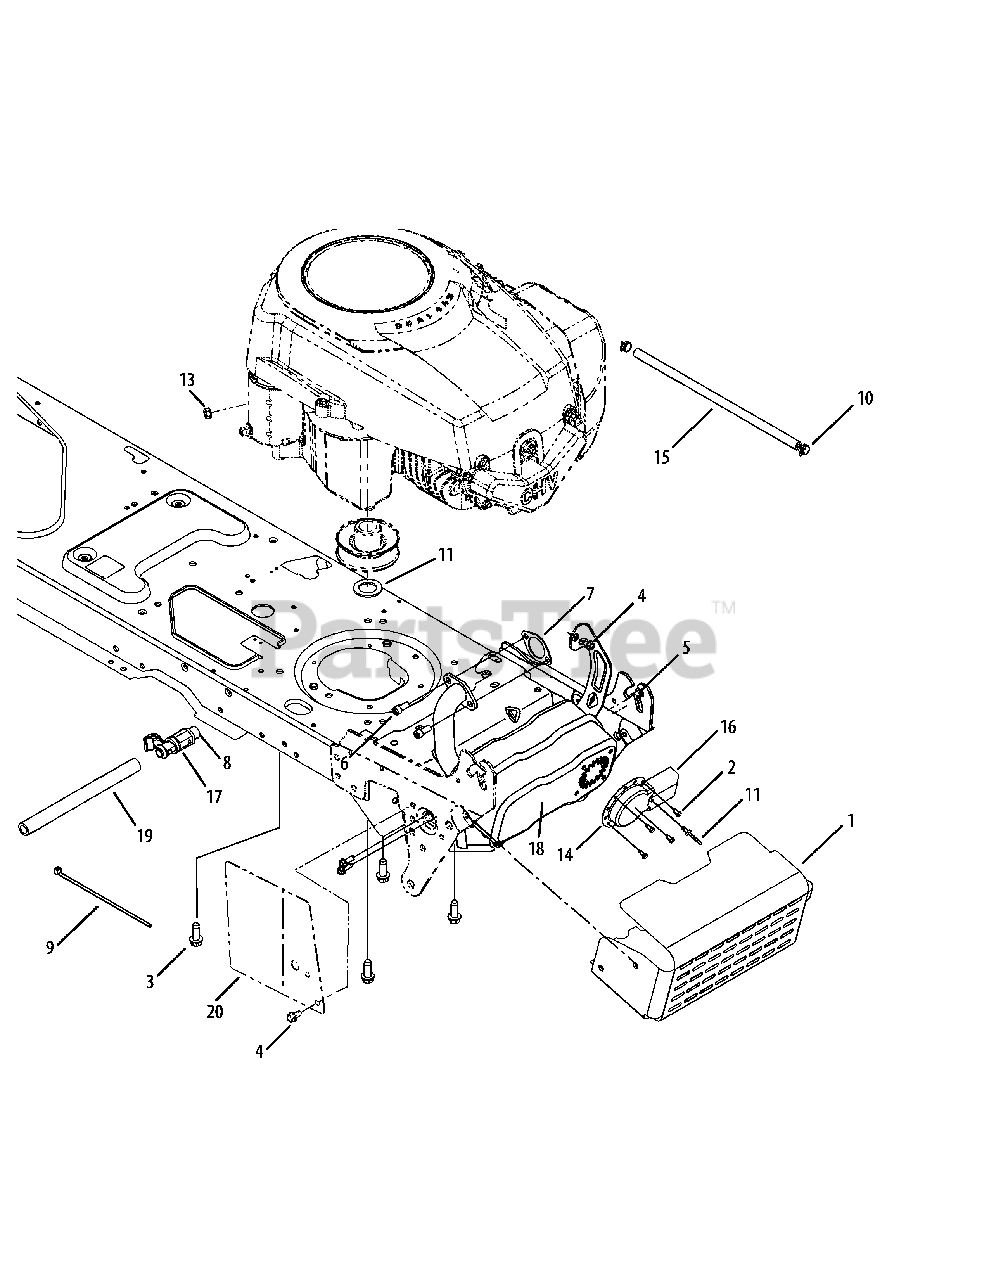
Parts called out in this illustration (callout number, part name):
1	Muffler Shield Assembly
2	Hex AB Scr #8-18 x .50
3	TT Screw 3/8-16 x 1.00
4	Hex Wash S-Tapp Scr 1/4-20 x .50
5	Thd Forming Scr. 1/4-20 x .75 Lg.
6	Scr. 5/16-18 x .75
7	Exhaust Gasket
8	Pipe Seal ant Locktite 567
13	Hex Sems Nut 1/4-20
14	Muffler Deflector
16	Long Muffler Deflector
18	Muffler
19	Oil Drain Hose
